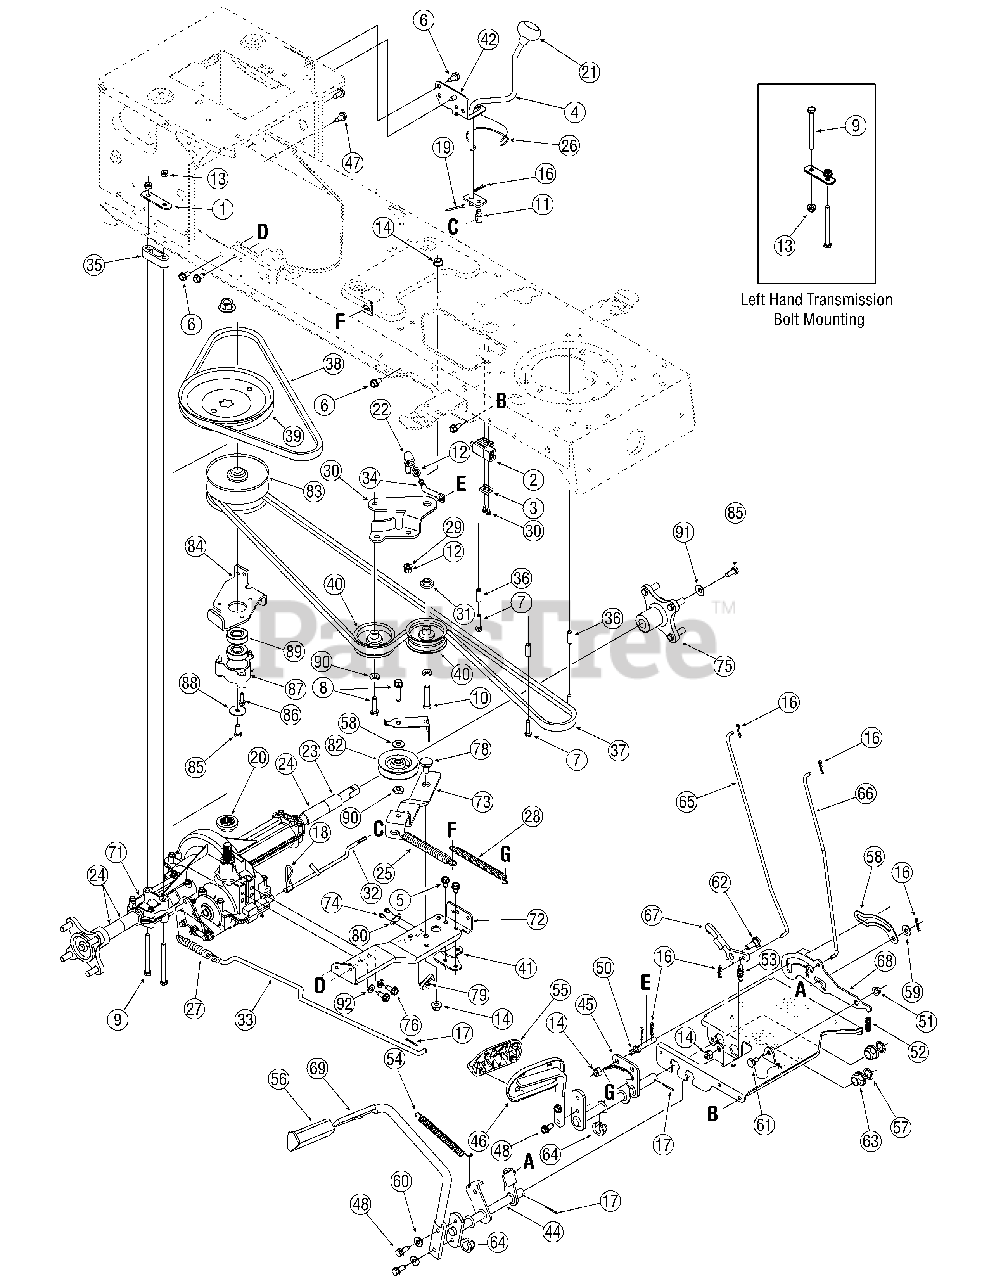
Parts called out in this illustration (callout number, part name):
2	Switch, Interlock
3	Plate, Switch
4	Lever Assembly, Shift
5	Screw, 5/16-18, 0.500
6	Screw, 5/16-12, 0.750
7	Screw, 1/4-20, 1.250
8	Screw, Sems, 3/8-16, 1.500
9	Screw, 5/16-18, 3.50, Gr5
10	Screw, 3/8-16, 2.00, Gr5
11	Adjustment Ferrule 1/4-20 x 1.
12	Nut, Hex, 3/8-24, Gr5
13	Nut, Flange Lock, 5/16-18, GrF, Nylon
14	Nut, Flange Lock, 3/8-16, GrF, Nylon
15	Nut, Flange, 9/16-18, Gr2
16	Pin, Cotter, .072 Dia. x 1.13
17	Pin, Cotter, 3/32, 1.0
18	Cotter Pin, Internal, .125 Dia.
19	Pin, Cotter, 1/8 x 1.25
20	Pulley Hub, 5/8 Spline
21	Knob, Shift
22	Ball Joint
23	Sleeve, .758 x .821 x 1.5
24	Sleeve, .758 x .821 x 2.4375
25	Spring, Extension, .76 Dia x 6.12
26	Spring Clip, Shifter
27	Spring, Extension, .59 OD x 4.00
28	Spring, Extension, .50 Dia x 6.37
29	Washer, Lock, 3/8
30	Screw, #10-16, .50
31	Spacer, Shoulder, 1.00 x .38 x .38
33	Rod, Brake
34	Idler Rod, Adjustable, 3/8
35	Spacer, .68
36	Spacer, .260 x .372 x 1.030
37	Belt, V-Type
38	Belt, V-Type
39	Pulley, V-Type, 7.25 Dia.
40	Idler Pulley, Flat 2.75 OD
41	Bracket, Shift
42	Bracket, Shift, F-N-R
47	Screw, M8 x 1.25 x 20 mm
48	Screw,5/16-18, 0.750
49	Screw, 5/16-18, 0.750
50	Pin, 3/8-16 x 2.68
51	Nut, Flange Lock, 5/16-18, Gr5
52	Spring, Compression, .405 x 1.17
53	Spring, Extension, .50 OD x 1.41
54	Spring, Extension, .50 OD x 6.37
56	Pad, Brake
57	Washer, Flat, .64 x 1.24 x .06
58	Washer, Flat, .385 x .870 x .092
59	Washer, Flat, .406 x .875 x .059
60	Washer, Lock, 5/16
61	Screw, Shoulder .437 Dia x .162
62	Screw, Shoulder, .50 x .27 Lg, 3/8-16
63	Bearing, Hex Flange
64	Split Bearing, Hex Flange
65	Rod, Brake Lock
66	Rod, Cruise Control
67	Latch, Cruise Control
68	Bracket, Lockout
71	Transmission, Single Speed
72	Bracket Assembly, Torque
73	Bracket, Idler
74	Screw, #8-18 x .50
75	Hub Assembly, Wheel
76	Screw, 5/16-18, .625
77	Screw, 3/8-16, 1.12
78	Screw, Shoulder, .625 x .217
79	Switch Spring, Short
80	Plate, Insulator
81	Spacer, Shoulder
82	Pulley, V-Type, 3.06
83	Pulley Assembly, Variable Speed
84	Bracket, Pulley
85	Screw, 5/16-24, .750
86	Screw, 1/4-20, 1.50
87	Cup, Bearing
88	Washer, Flat
89	Ball Bearing
90	Washer, Flat, .407 x .812 x 135
91	Washer, Bell, .340 x .872 x .060
92	Washer, Flat, .330 x .630 x .063
